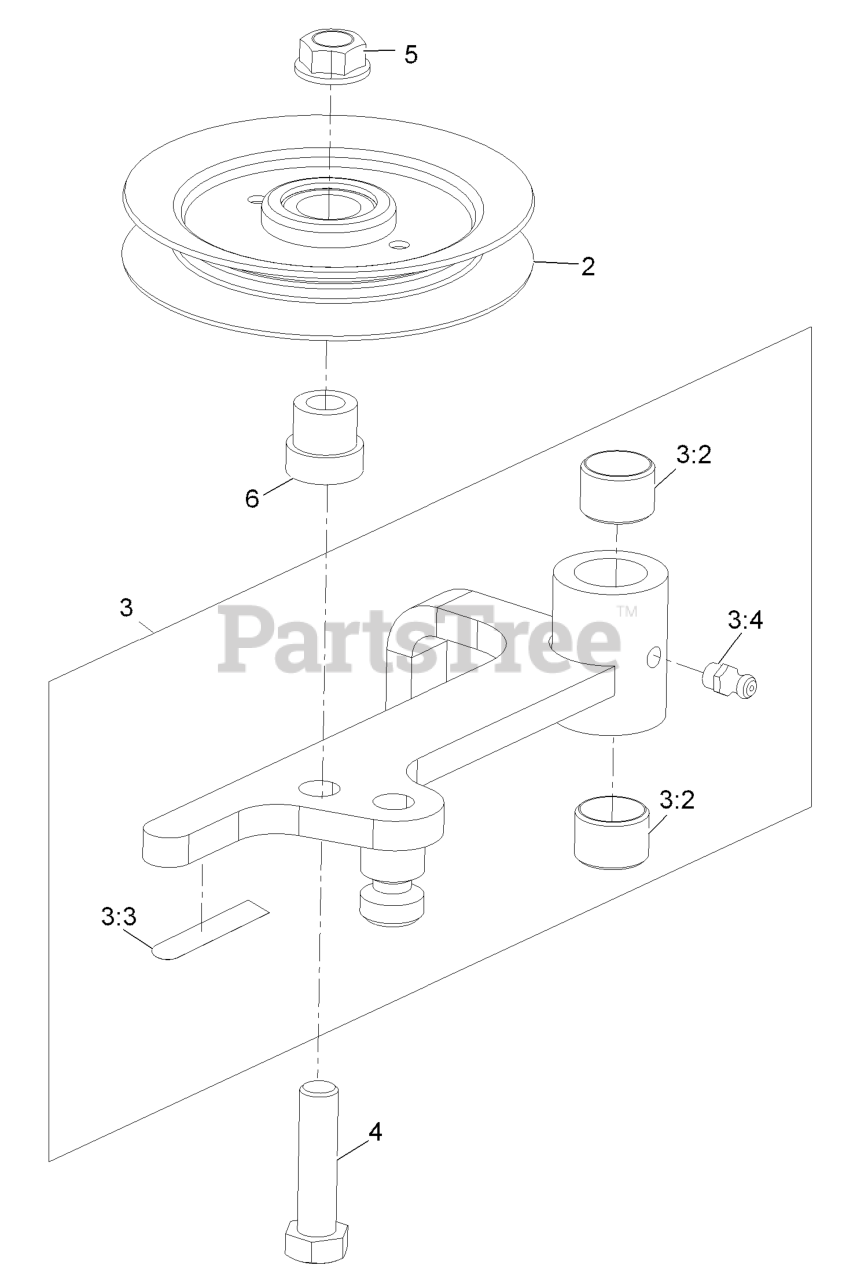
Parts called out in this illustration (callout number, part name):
3	ASM, IDLER ARM - SERVICE
3:2	BUSHING
3:3	DECAL-WARNING
3:4	FITTING-GREASE
4	SCREW-HH
5	NUT-HHF, WHIZ
6	HUB,SPACER
